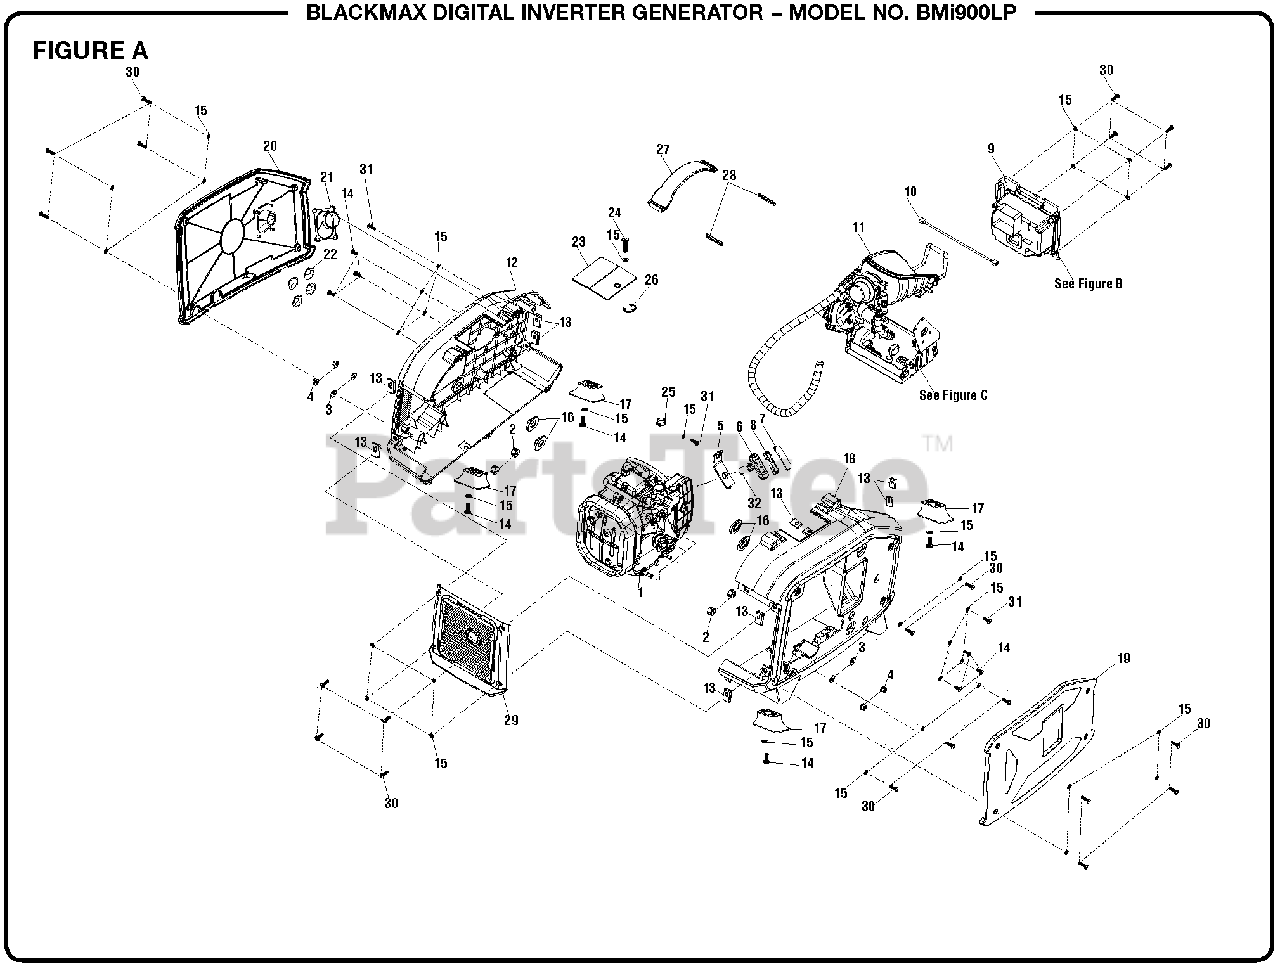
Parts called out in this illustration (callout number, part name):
1	Engine
2	Side Engine Isolator
3	Rubber Washer (ID6.25 x OD15.5 x 2t)
4	Lock Flange Nut (M6)
5	Starter Cover
6	Recoil Handle
7	Recoil Handle Cover
8	Recoil Handle Plastic Support
9	Control Panel Assembly
10	Stepper Motor Extended Wire Harness
11	Fuel System & Bracket Assembly
12	Panel Housing (Right)
14	Screw (M5 x 12 mm,T-25 Torx Hd.)
15	Washer (ID5.2 x OD10 x 1t)
16	Rubber Grommet
17	Rubber Foot w/Metal Insert and Ribs
18	Panel Housing (Left)
19	Maintenance Panel (Left)
20	Maintenance Panel (Right)
21	Rubber Grommet
22	Internal Tooth Washer (ID5)
23	Spark Plug Door
24	Screw (M5 x 16 mm, T-25 Torx Hd.)
25	Fuel Hose Clamp
26	E-Clip Lock Washer
27	Rubber Handle (Upper)
28	Side Lock (U-Shaped)
29	Muffler Cover
30	Screw (M5 x 18 mm, T-25 Torx Hd.)
31	Screw (M5 x 16 mm, T-25 Torx Hd.)
32	Rubber Grommet Handle
